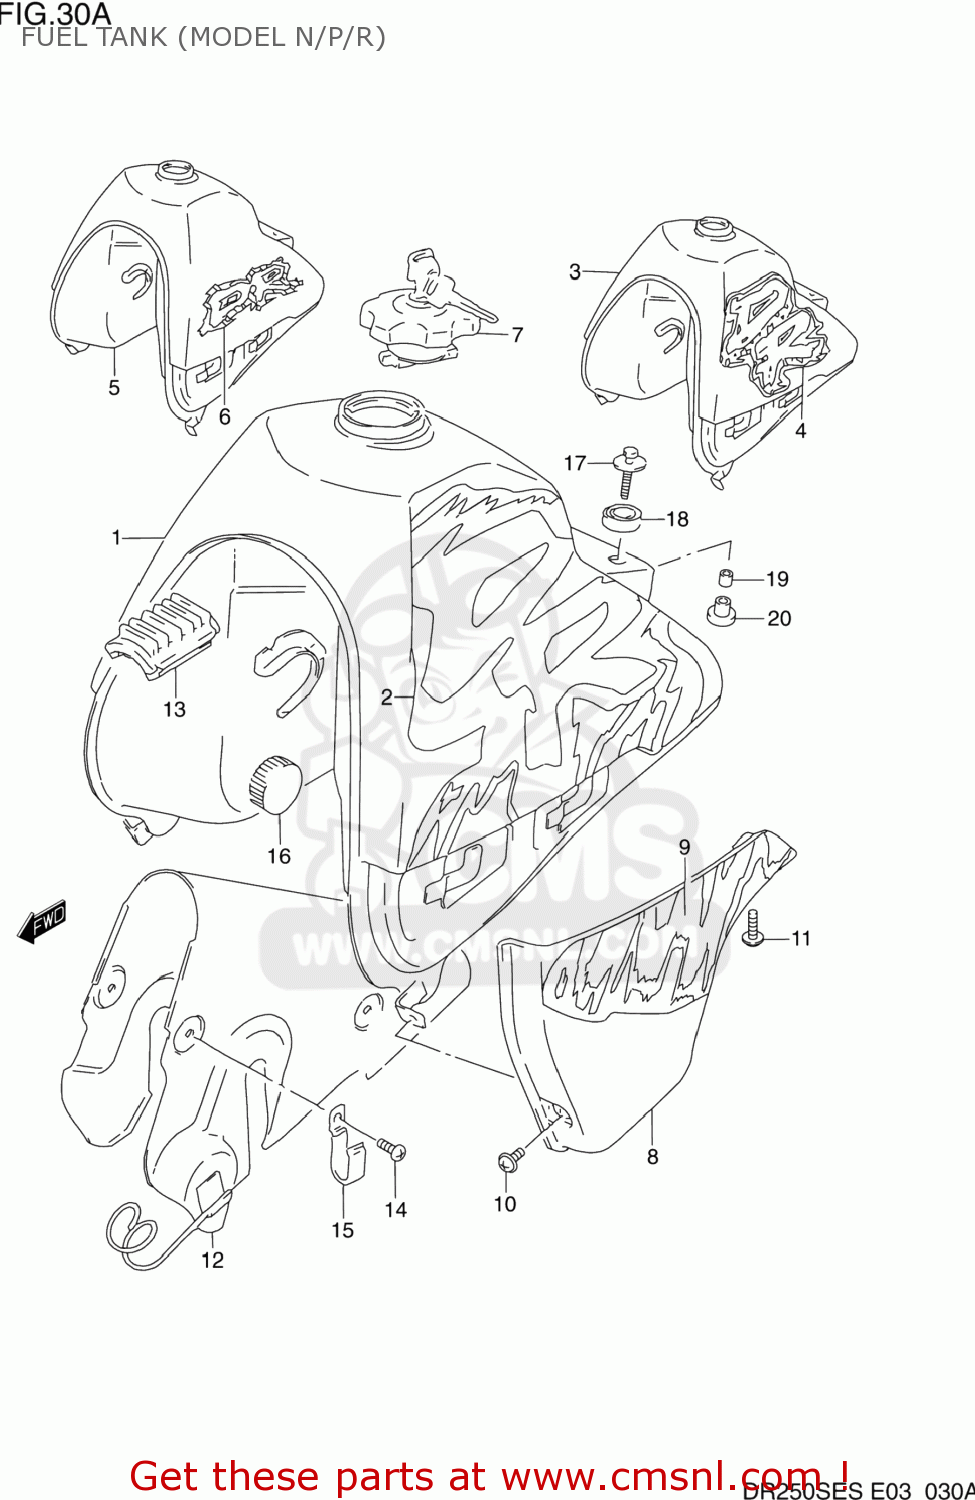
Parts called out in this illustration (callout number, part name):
1	TANK ASSEMBLY,FUEL
2	TAPE SET,FUEL TANK
3	TANK ASSEMBLY,FUEL
4	TAPE SET,FUEL TANK
5	TANK ASSEMBLY,FUEL
6	TAPE SET,FUEL TANK
7	CAP SET,FUEL TANK
8	COVER,FUEL TANK,R
9	TAPE,FUEL TANK STRIPE
10	SCREW
11	SCREW(6X12)
12	SHIELD,FUEL TANK
13	CUSHION,FUEL TANK FR UPR
14	BOLT
15	CLAMP
16	CUSHION
17	BOLT
18	CUSHION
19	SPACER
20	CUSHION
